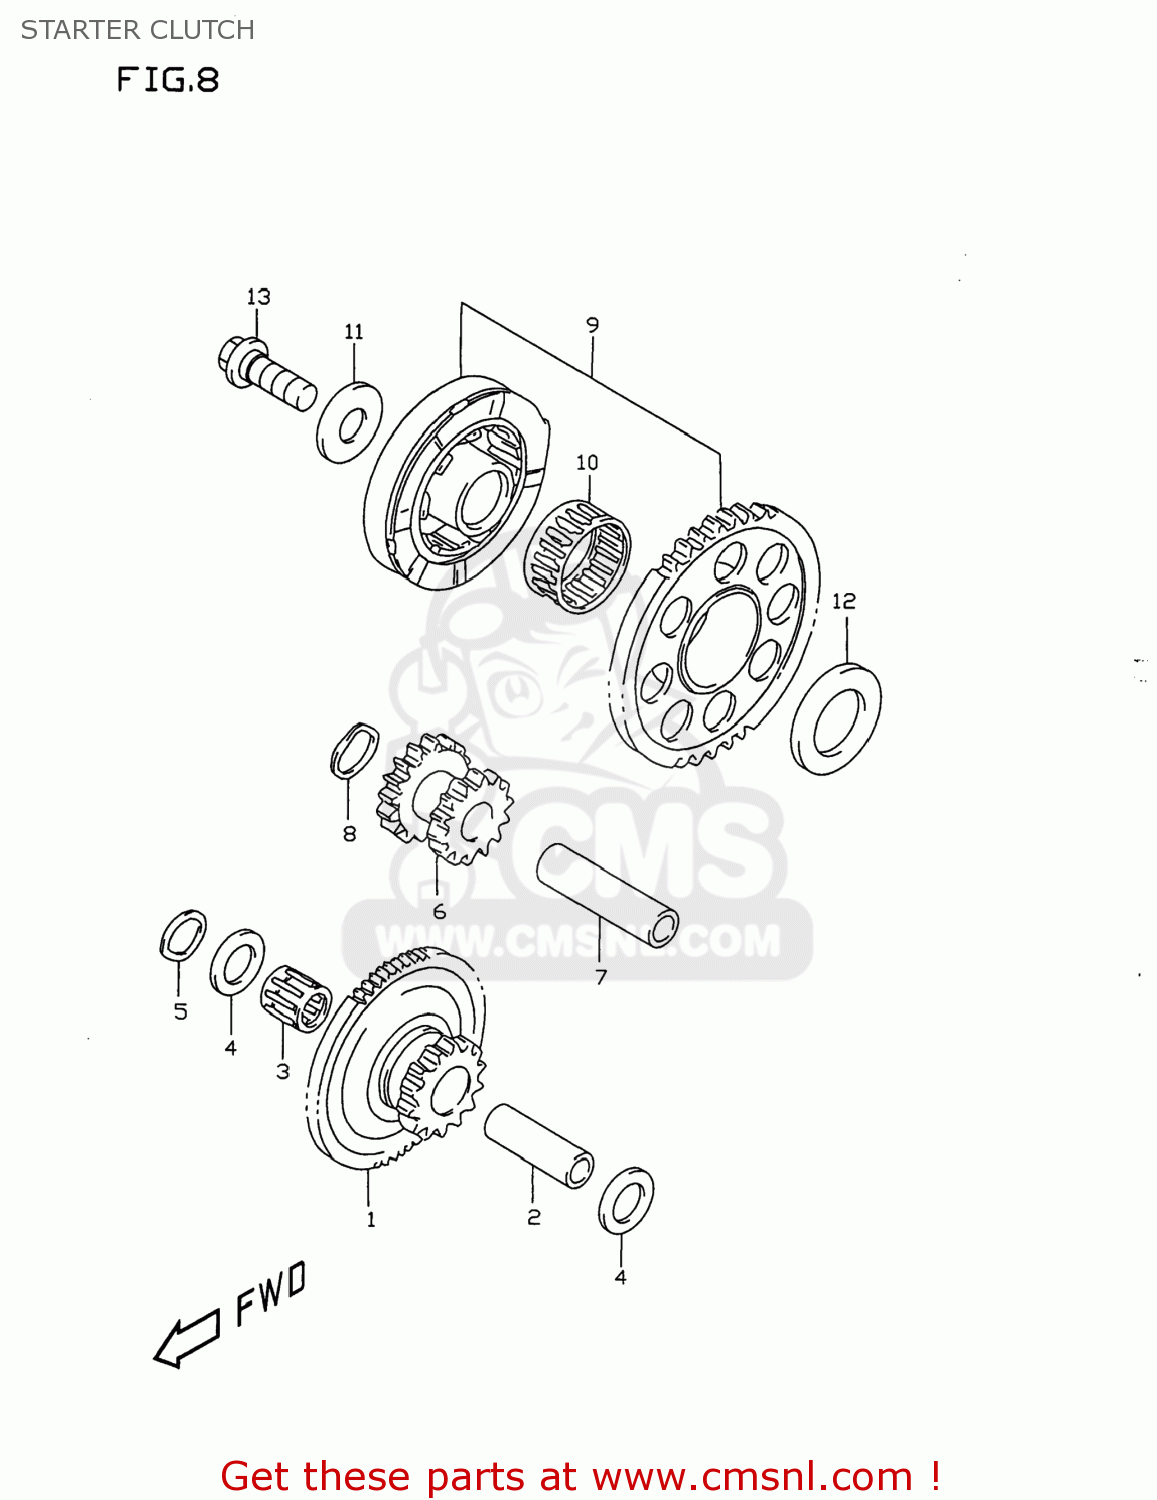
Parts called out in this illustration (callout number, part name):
1	GEAR,STARTER IDLE NO.1
2	PIN,PISTON
3	BEARING(12X16X16)
4	WASHER
5	WASHER
6	GEAR,STARTER I
7	PIN ,PISTON
8	WASHER
9	CLUTCH SET,STARTER
10	BEARING(28X34X16.8)
11	WASHER
12	WASHER
13	BOLT(10X23)
